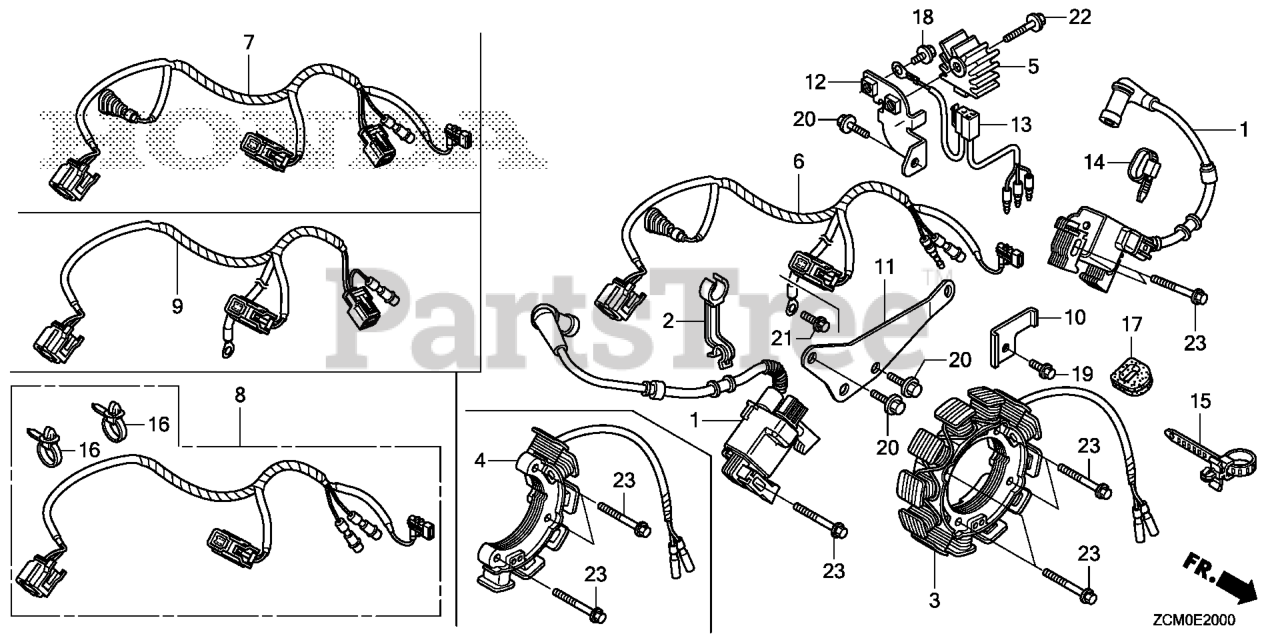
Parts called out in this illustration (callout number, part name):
1	COIL ASSY., IGNITION
2	CLAMP, IGNITION WIRE
4	COIL ASSY., CHARGE (2.7A)
8	WIRE HARNESS ASSY., ENGINE
10	BRACKET, HARNESS
11	BRACKET, HARNESS
14	BAND, WIRE (95MM)
15	STRAP, CABLE (105MM) *NH1* (Honda Code 1685536). (BLACK)
16	CLIP, HARNESS BAND (145MM) (BLACK)
17	GROMMET, CORD
19	BOLT, FLANGE (6X12) Use up to Engine SN 1543277.
20	BOLT, FLANGE (6X14)
23	BOLT, FLANGE (6X32)
